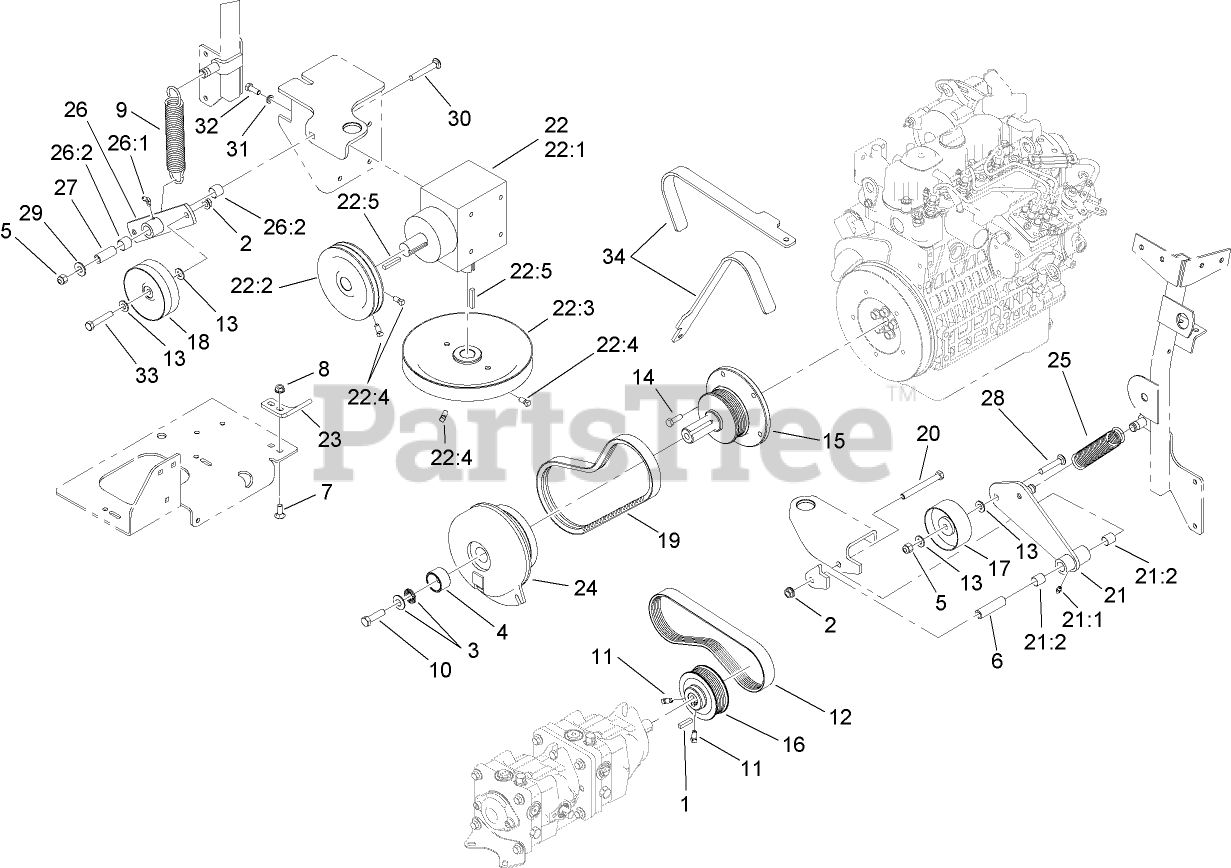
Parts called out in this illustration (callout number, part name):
2	NUT-HHF, WHIZ
3	WASHER-SPRING
4	RETAINER-CLUTCH
5	NUT-LOCK, NI
6	BUSHING-PIVOT, IDLER
7	SCREW-CARR
8	NUT-HF
9	SPRING-EXTENSION
10	SCREW-HH
11	SCREW-SET
12	BELT-V
13	WASHER-FLAT
14	SCREW-HH
15	SHAFT-STUB
16	PULLEY
17	PULLEY-FLAT
18	PULLEY-FLAT
19	BELT-V
20	SCREW-HH
21	PUMP IDLER ARM ASM
21:1	FITTING-GREASE
21:2	SLEEVE-BEARING
22	Gearbox ASM
22:1	GEARBOX-90 DEG
22:2	PULLEY
22:3	PULLEY
22:4	SCREW-SET
22:5	KEY-SQUARE
23	BRACKET-STOP, CLUTCH
24	CLUTCH-ELECTROMAGNETIC
25	SPRING-EXTENSION
26	GEARBOX IDLER ARM ASM
26:1	FITTING-GREASE
26:2	SLEEVE-BEARING
27	BUSHING
28	SCREW-CARR
29	WASHER-FLAT
30	SCREW-CARR
31	WASHER-LOCK
32	SCREW-HH
33	SCREW-HH
34	TOOL-ALIGNMENT, PULLEY
